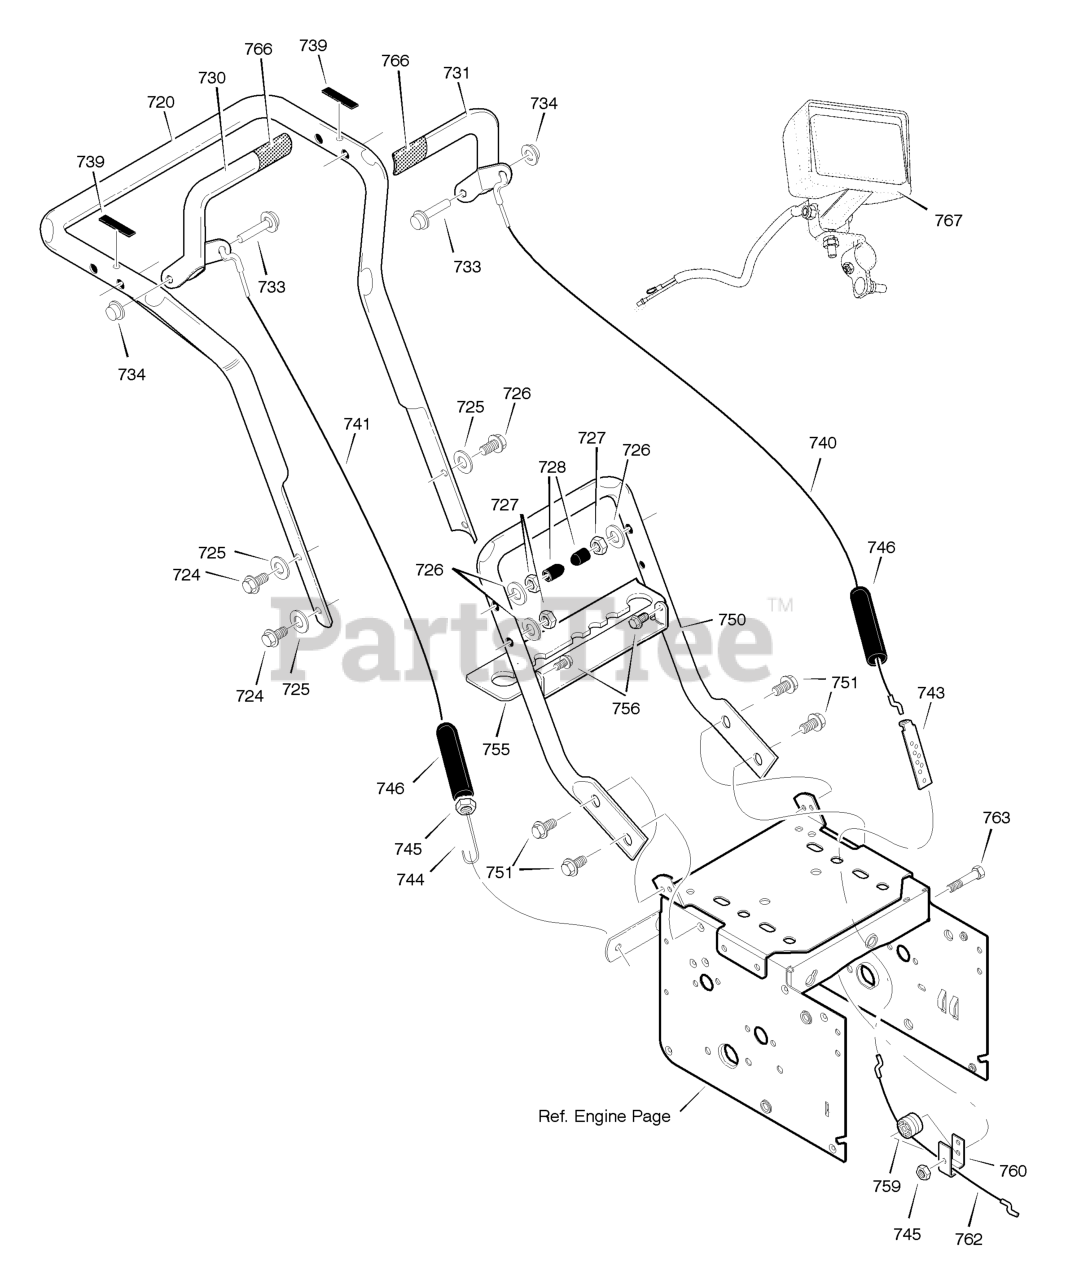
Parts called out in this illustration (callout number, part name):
720	HANDLE, UPPER
724	SCREW, 5/16-18 x 2.75
725	WASHER, FLAT
726	WASHER, SPTLK .31X.58X.08
727	NUT, 5/16-18 REGHEX
728	STOP, RED PLASTIC
730	CLUTCH HANDLE, RIGHT
731	CLUTCH HANDLE, LEFT
733	PIN, PIVOT CLUTCH
734	NUT, PUSH ON CAP
739	BUMPER, RECTANGLE
740	CABLE, CLUTCH 28.44L
741	CABLE, AUGER CLUTCH
743	BRACKET, CABLE ADJUSTER
744	SPRING, AUGER CLUTCH
745	NUT, 1/4-20
746	BOOT, CLUTCH SPRING
750	HANDLE, LOWER
751	SCREW, TAP 5/16-18 X .75
755	BRKT, GEAR SELECTOR
756	SCREW, 1/4-20 X 0.63
759	SPOOL-CABLE, AUGRT CLUTCH
760	BRACKET, CABLE SPOOL YZ
762	CABLE, LOWER DRIVE 12"
763	BOLT, HEX 1/4-20 X 1.50
767	HEADLIGHT
